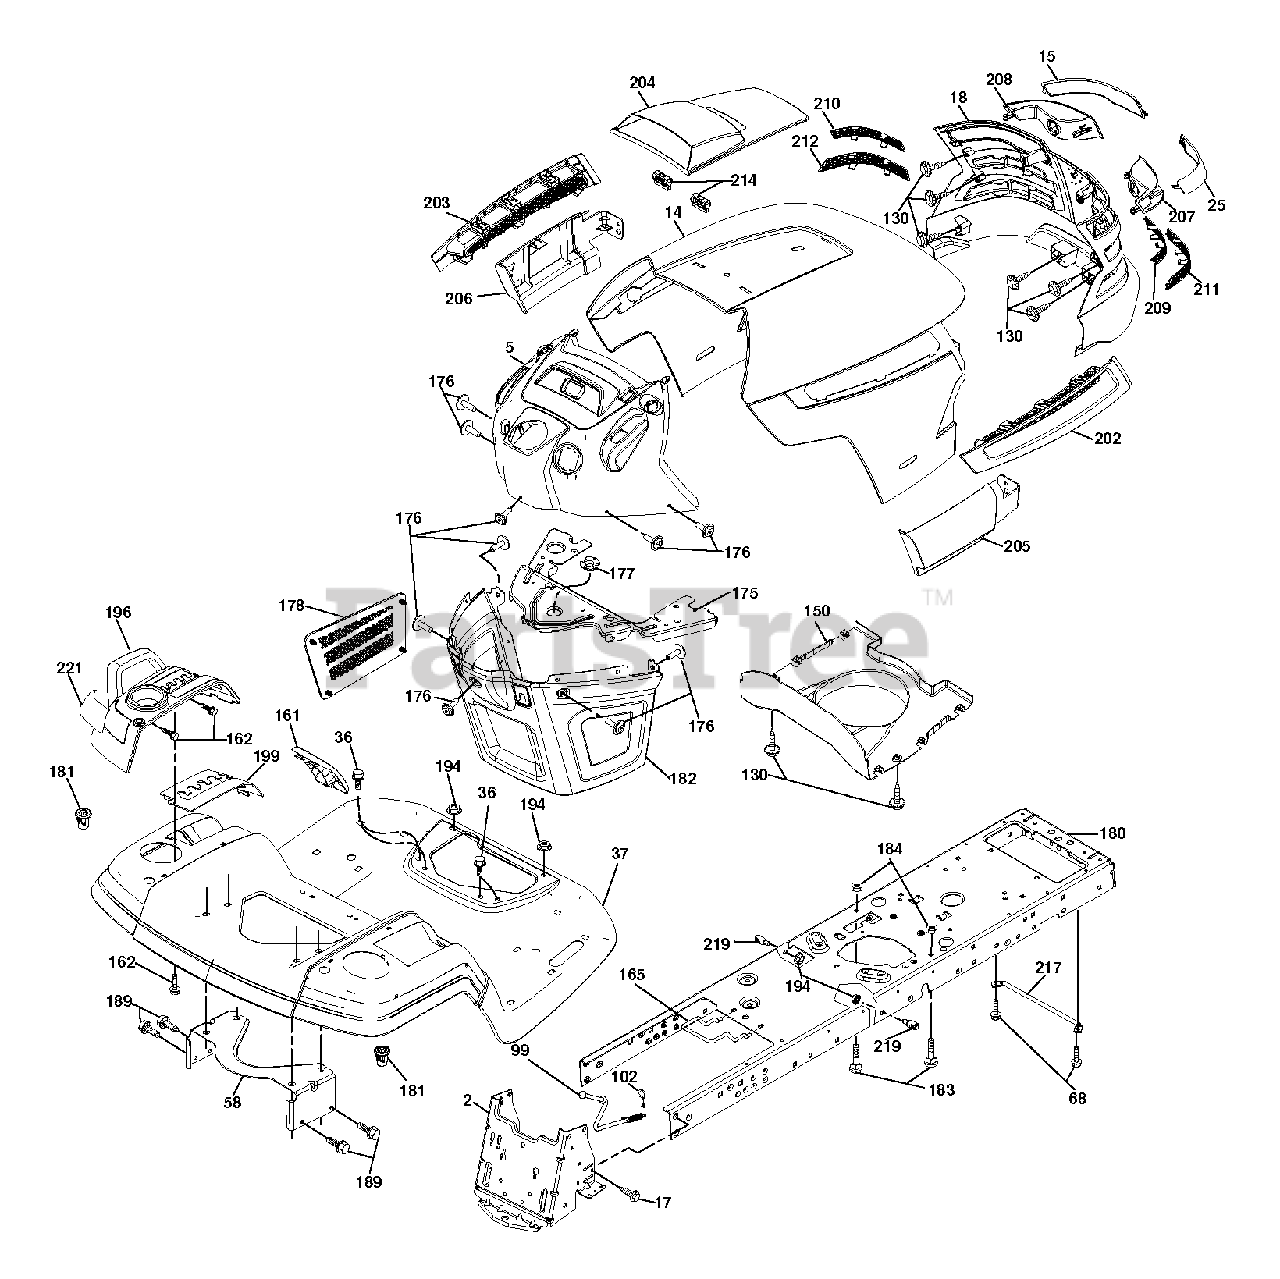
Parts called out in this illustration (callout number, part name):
2	Drawbar
14	Hood
17	Screw 3/8-16 x .75
18	Grille/Lens Asm.
36	Screw 5/16-18 x 3/4
37	Fender
58	Bracket Support Fender
68	Screw Thdrol 5/16-18 x 1/2
99	Rod Asm Bypass
102	Retainer Spring
130	Screw 10 x 3/4 Single Lead Hex
161	Console Fuel Window
165	Support Tank Rear
175	Crossmember
176	Screw #10-24 x 5/8 Rnd Qudrx Gim
177	Bushing Steering
178	Cargo Asm. Net
180	Chassis
181	Bushing Mtg. Fender Crgo
182	Dash Lower
183	Bolt Fin Hex 5/16-18 unc x 1-1/4
184	Spacer Fender
189	Screw 5/16-18 x 3/4
194	Nut Lock Hex Flange 5/16-18
194	Plug 12V Adapter Caplug
196	Console Asm. Deck Lift
199	Plate Deck Lift
202	Vent Side Hood RH
203	Vent Side Hood LH
204	Vent Top
205	Skirt Side RH
206	Skirt Side LH
209	Insert Hex Top RH
210	Insert Hex Top LH
211	Insert Hex Bot. RH
212	Insert Hex Bot. LH
214	Clip Retainer Tinner
217	Rod Pivot Chassis/Hood
219	Stud Fastener
221	Reflector LH
